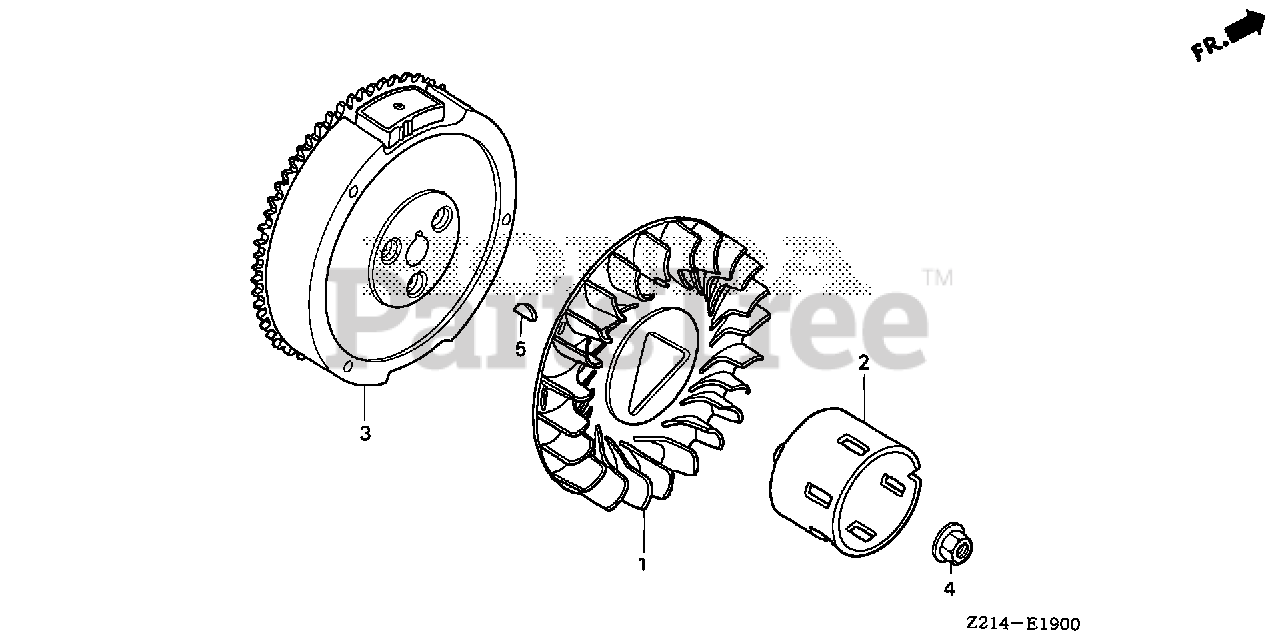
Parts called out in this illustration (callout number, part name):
1	FAN, COOLING
2	PULLEY, STARTER
3	FLYWHEEL (SEL-LAMP)
4	NUT, SPECIAL (16MM) (1)
4	NUT, SPECIAL (16MM)
5	KEY, SPECIAL WOODRUFF (25X18)
